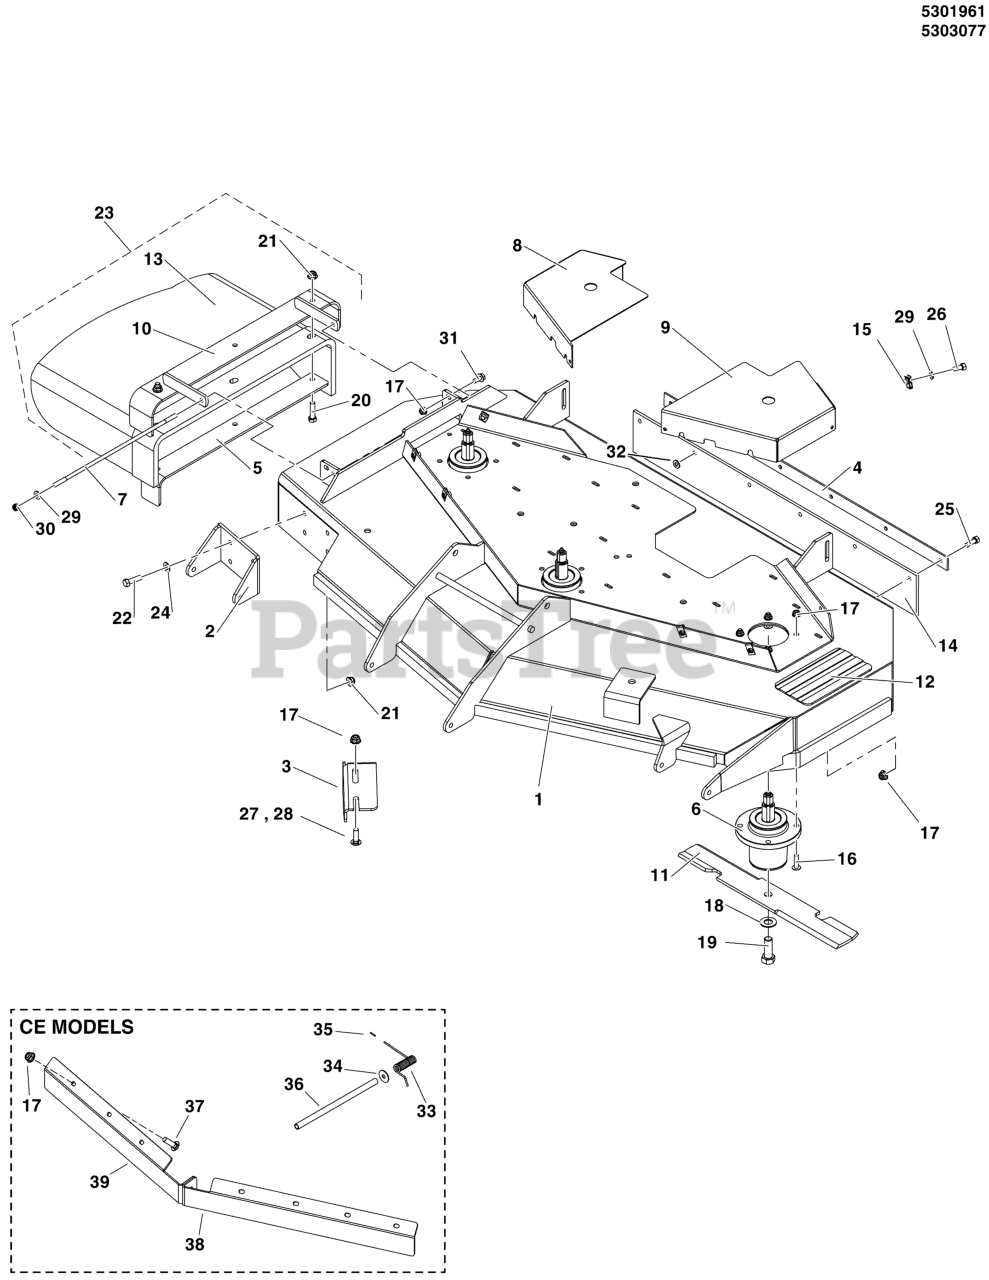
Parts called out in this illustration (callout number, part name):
1	DECK SHELL W/ DECALS, 52"
2	PLATE, BRACKET, ANTI SCALP, RH - 61 -RED
3	PLATE, DEFLECTOR, 52 DECK - BLK
4	PLATE, SUPPORT - BLKV
5	SUPPORT, DISCHARGE CHUTE, 61/72 - BLK
6	SPINDLE, ASSM, ALUMINUM - 5.25
7	ROD, MOUNT, CHUTE, 61, CZ
8	GUARD, 52" DECK - RH - RED
9	GUARD, 52 DECK, IS1500Z, LH - RED
10	WELD, FRAME, CHUTE, 61 / 72 - RED
11	BLADE, 18 X .25 X 2.5, 1 X 3.5 (SET OF THREE)
12	SAFETY WALK, 4.00 X 7.50
13	CHUTE, DISCHARGE, RUBBER, 61/72, BENT
14	FLAP, STRIPER, 61" DECK, IS3100, S200X
15	BODY CLIP, 5/16-18-7GA MATERIAL
16	BOLT, Flange Head, 5/16-18 x 1-1/4
17	NUT, 5/16-18 HEX NYLOCK FLANGE NUT
18	WASHER, BLADE BOLT, 9/16" F436, CZ
19	BOLT, 5/8-11 X 1-3/4 GD8
20	BOLT, 3/8-16 X 1-1/2" GD5 CZ
21	NUT, 3/8 - 16 HEX NYLOCK FLANGE
22	BOLT, 3/8-16 X 1-1/4" GD5 CZ
23	PURCHASE INDIVIDUAL REPLACEMENT PARTS
24	WASHER, 3/8 SAE
25	BOLT, 5/16-18 X 1" GRD5 YZ
26	BOLT, 5/16-18 X 3/4 GD5
27	BOLT, 5/16-18 X 3/4, CARRIAGE, GD5, CZ
28	BOLT, 5/16-18 X 1, CARRIAGE, GD5, CZ
29	WASHER, 5/16" SAE
30	NUT, 5/16-24 HEX NYLON LOCK
31	BOLT, 5/16-18 X 3/4 GD5
32	5/16" PUSH-ON NUT RETAINER, STL, CZ
33	SPRING, TORSION
34	WASHER, 5/16" Fender
35	CAP, PROTECTOR, .120 ID
36	TUBE, 1/2 X 3/8 BLACK POLY, 8.00 LG
37	BOLT, 5/16-18 X 1, CARRIAGE, GD5, CZ
38	BAFFLE, FRONT DISCHARGE, LH, S150XCE - RED
39	BAFFLE, FRONT DISCHARGE, RH, S150XCE-RED
